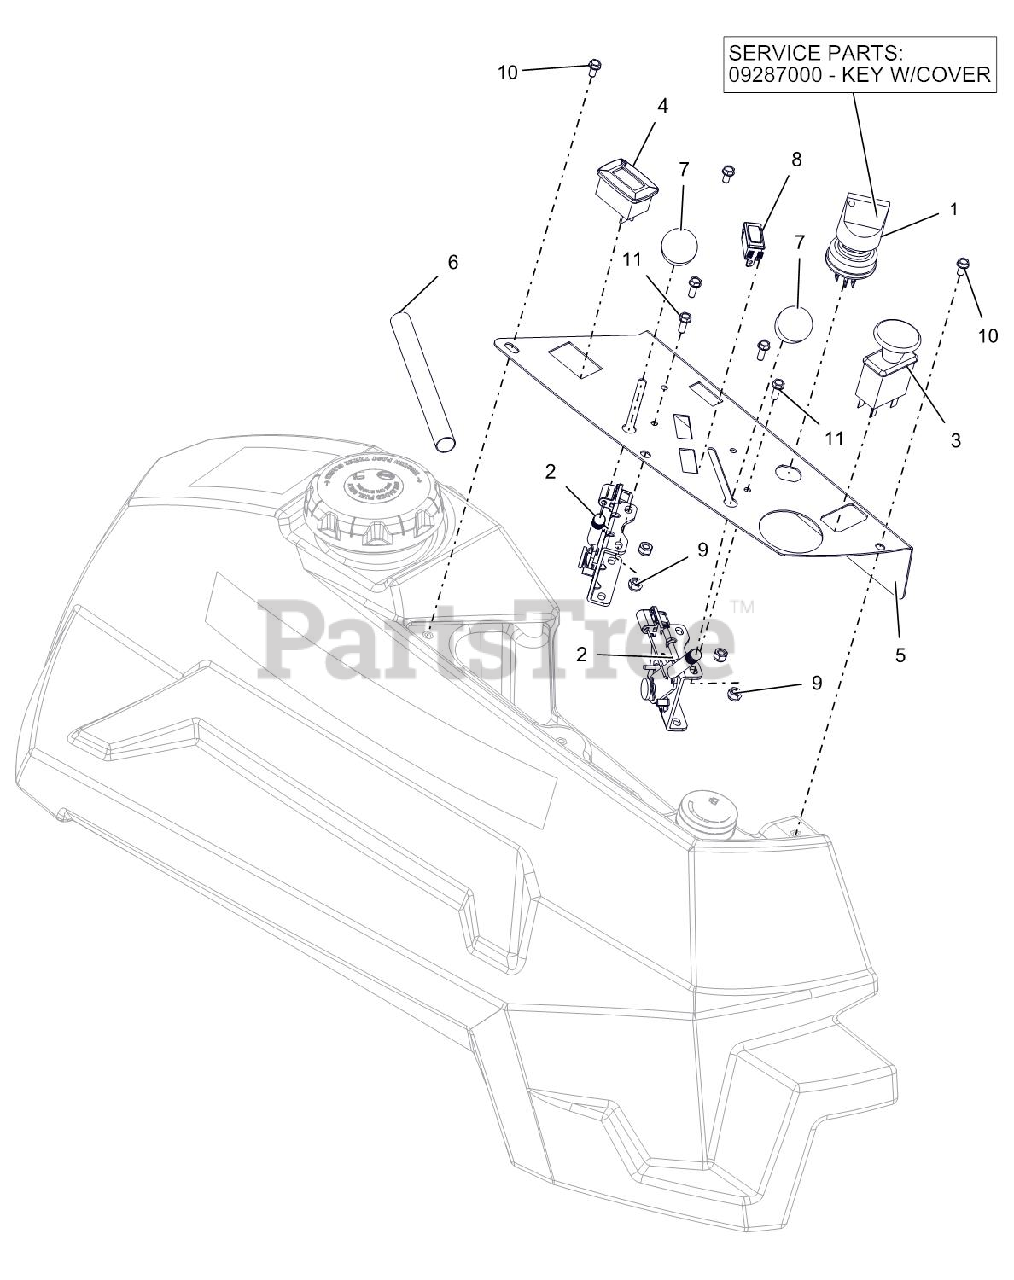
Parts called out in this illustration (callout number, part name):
1	KEY, W/ SHIELD
1	SWITCH, IGNITION
2	CABLE, PRO-CTRL 43.00"
3	SWITCH, CLUTCH
4	METER, HOUR W/MAINTENANCE
5	PT400 CONTROL PANEL - RED
6	SLEEVE, THERMAL 6"
7	KNOB-CONTROL-BLACK .38-16X.50
8	LIGHT,INDICATOR
9	@NUT-LK-NYL 10-24 W/INSRT YWZC
10	SCR-MCH 10-24X.38 HWHSTAINLESS
11	@SCR-MCH 10-24X.50 HWH YWZC
